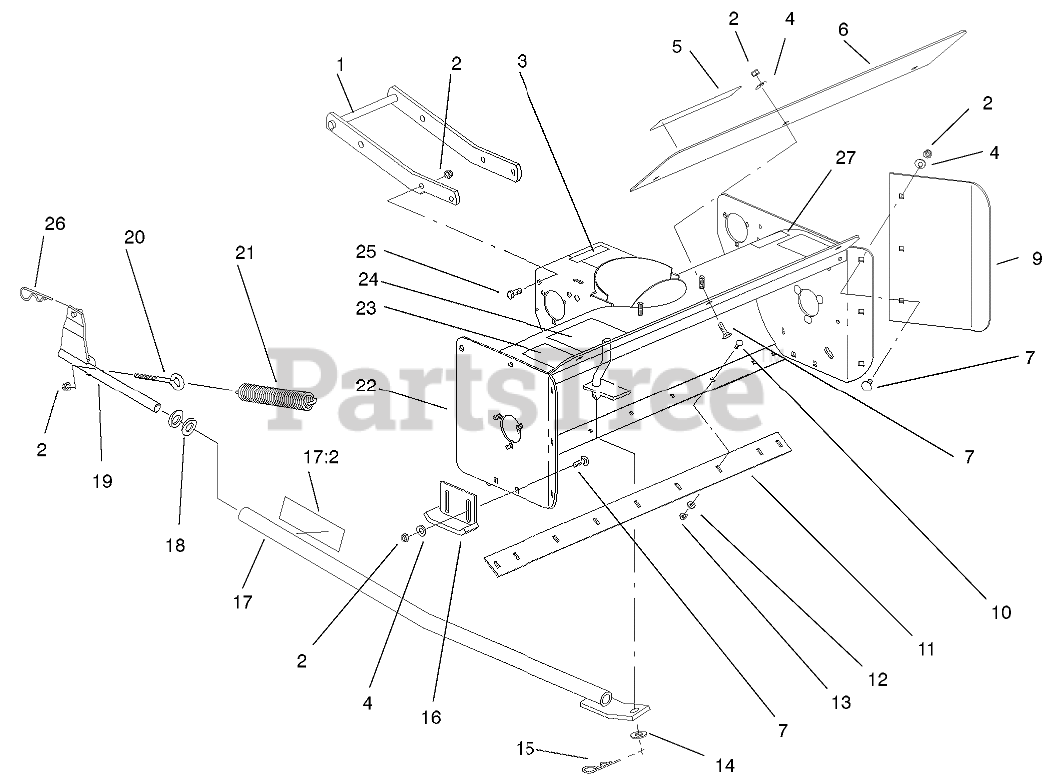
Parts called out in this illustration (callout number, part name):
1	FRAME-MOUNTING
2	NUT-LOCK, NI
4	WASHER-FLAT
5	DECAL-ATTACHMENT
6	PLATE-EXTENSION
7	BOLT-CARR
9	PLATE-EXTENSION, RH
10	SCREW-CARR
11	SCRAPER-REVERSIBLE
12	WASHER-FLAT
13	NUT-LOCK, NI
14	WASHER-FLAT
15	PIN-COTTER, HAIR
17	LIFT TUBE W/DECAL ASM
17:2	DECAL - WARNING
18	WASHER-FLAT
19	ROD-LIFT
20	EYEBOLT
21	SPRING
22	AUGER W/DECALS ASM
23	DECAL-DANGER
24	DECAL-WARNING
25	SCREW-HH
26	PIN-HAIR
27	DECAL - WARNING
